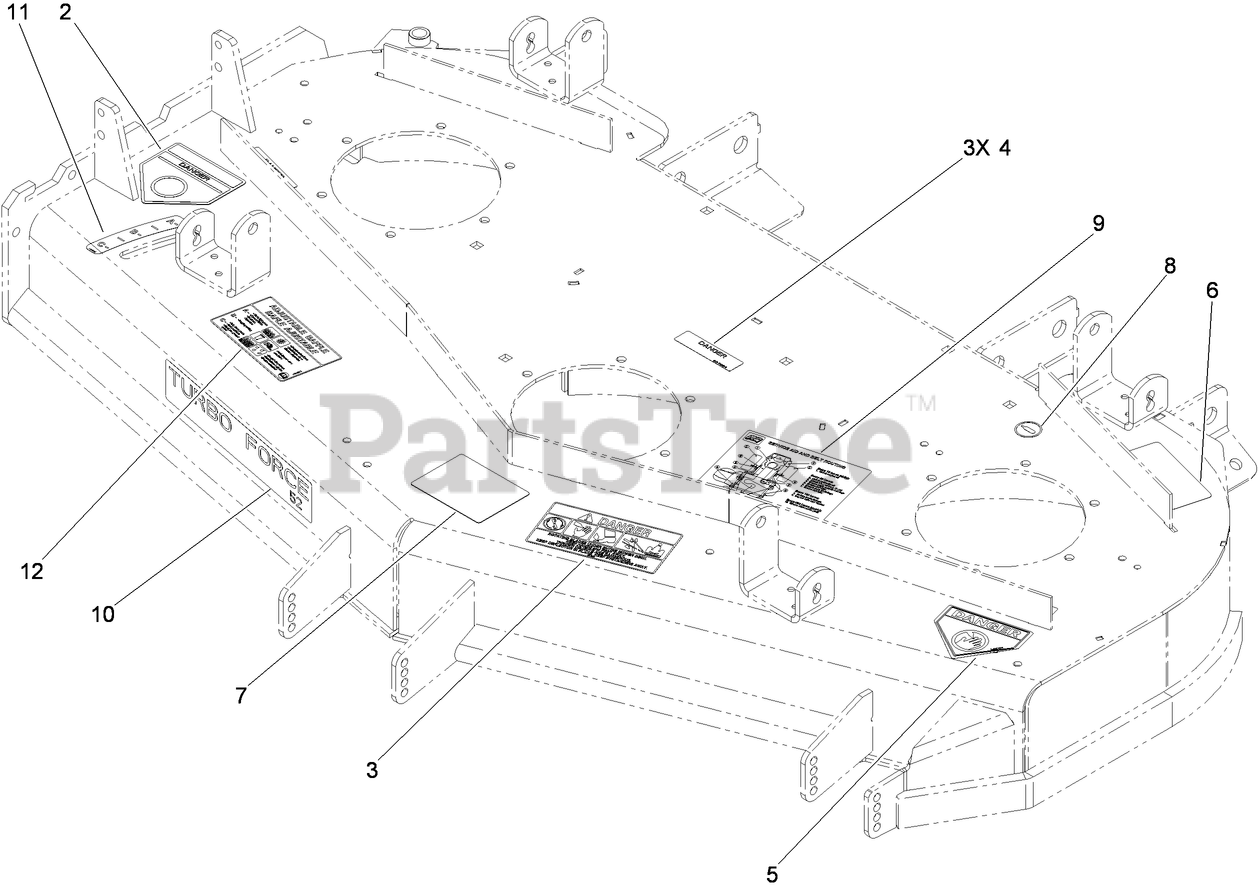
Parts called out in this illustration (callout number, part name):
2	DECAL-DANGER
3	DECAL-DANGER, THROWN OBJECT
4	DECAL-COVER, MISSING
5	DECAL-DANGER
6	DECAL-TORQUE
7	DECAL-SCALP, ANTI
8	DECAL-GREASE
9	DECAL-AID, SERVICE
11	DECAL-SETTING, BAFFLE
12	DECAL-ADJUSTMENT, BAFFLE
